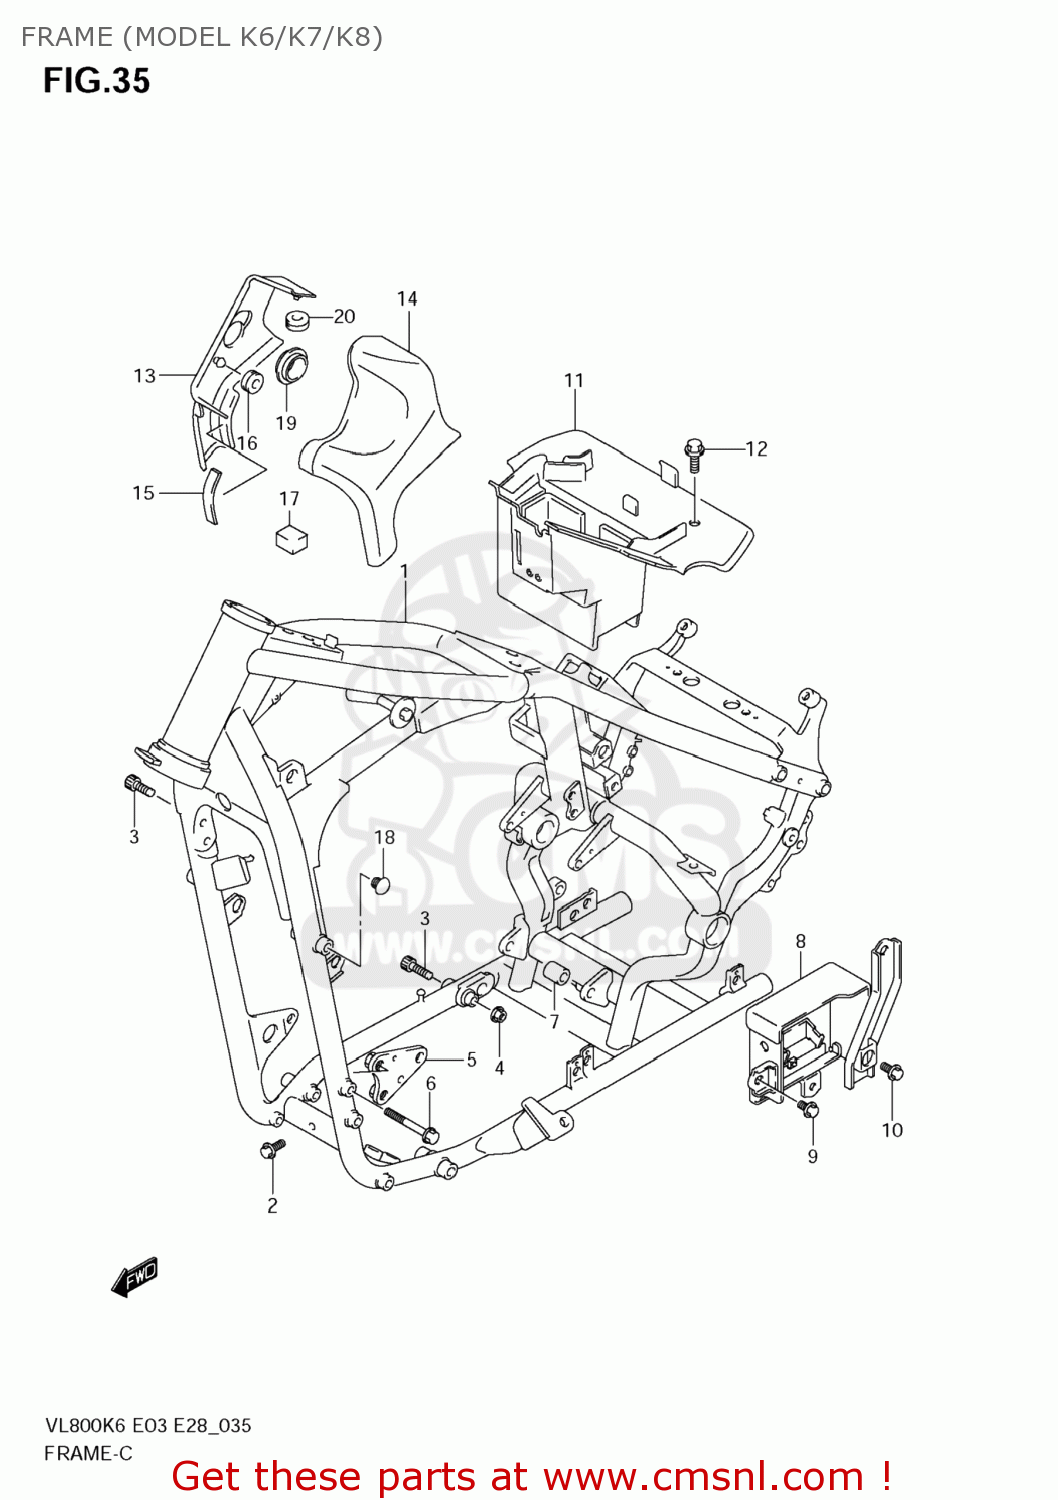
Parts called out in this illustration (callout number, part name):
1	FRAME
2	BOLT
3	BOLT
4	NUT
5	PLATE,ENGINE MOUNT NO.1,L
6	BOLT(8X65)
7	SPACER,ENG MTG LR
8	HOLDER COMP,EL
9	BOLT
10	BOLT
11	HOLDER,ELECTRI
12	BOLT(6X16)
13	COVER,FRAME HEAD,R(BLACK)
14	COVER,FRAME HE
15	CUSHION,FR FENDER
16	CUSHION
17	CUSHION
18	CAP(OD:14)
19	CAP
20	CUSHION
